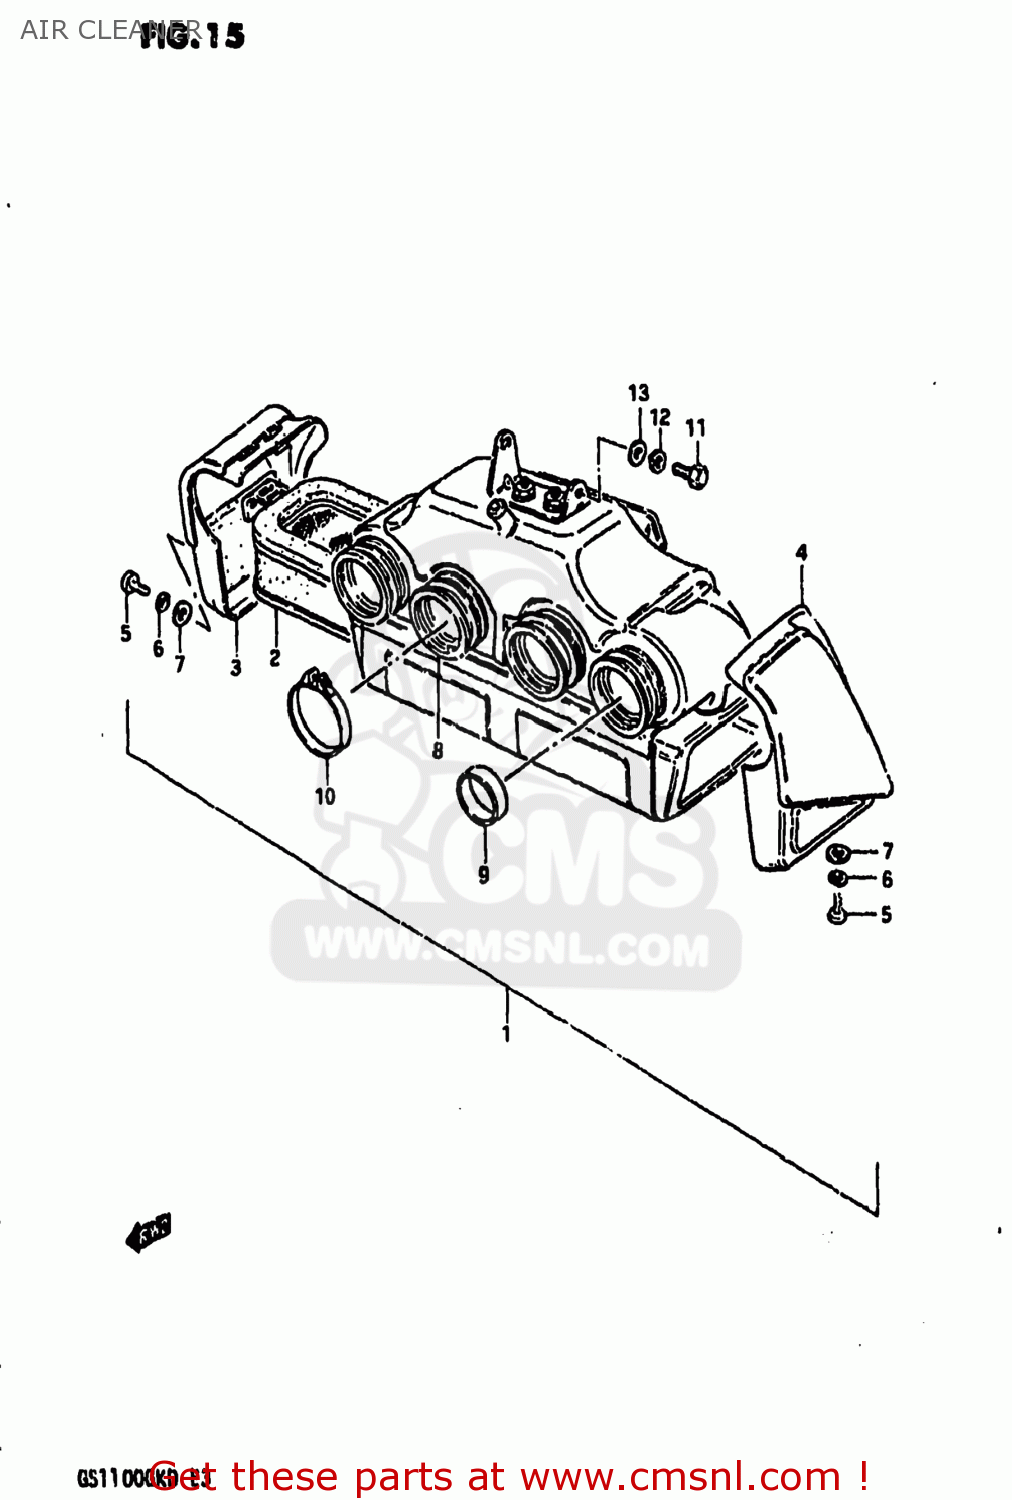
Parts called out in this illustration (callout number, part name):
1	CLEANER ASSEMBLY,AIR
2	FILTER ASSY
3	CAP,AIR CLEANER
4	CAP,AIR CLEANER
5	SCREW
6	LOCK WASHER
7	WASHER
8	TUBE,OUTLET
9	RING,CARBURETOR AIR IN
10	CLAMP
11	BOLT
12	LOCK WASHER
13	WASHER 6MM
